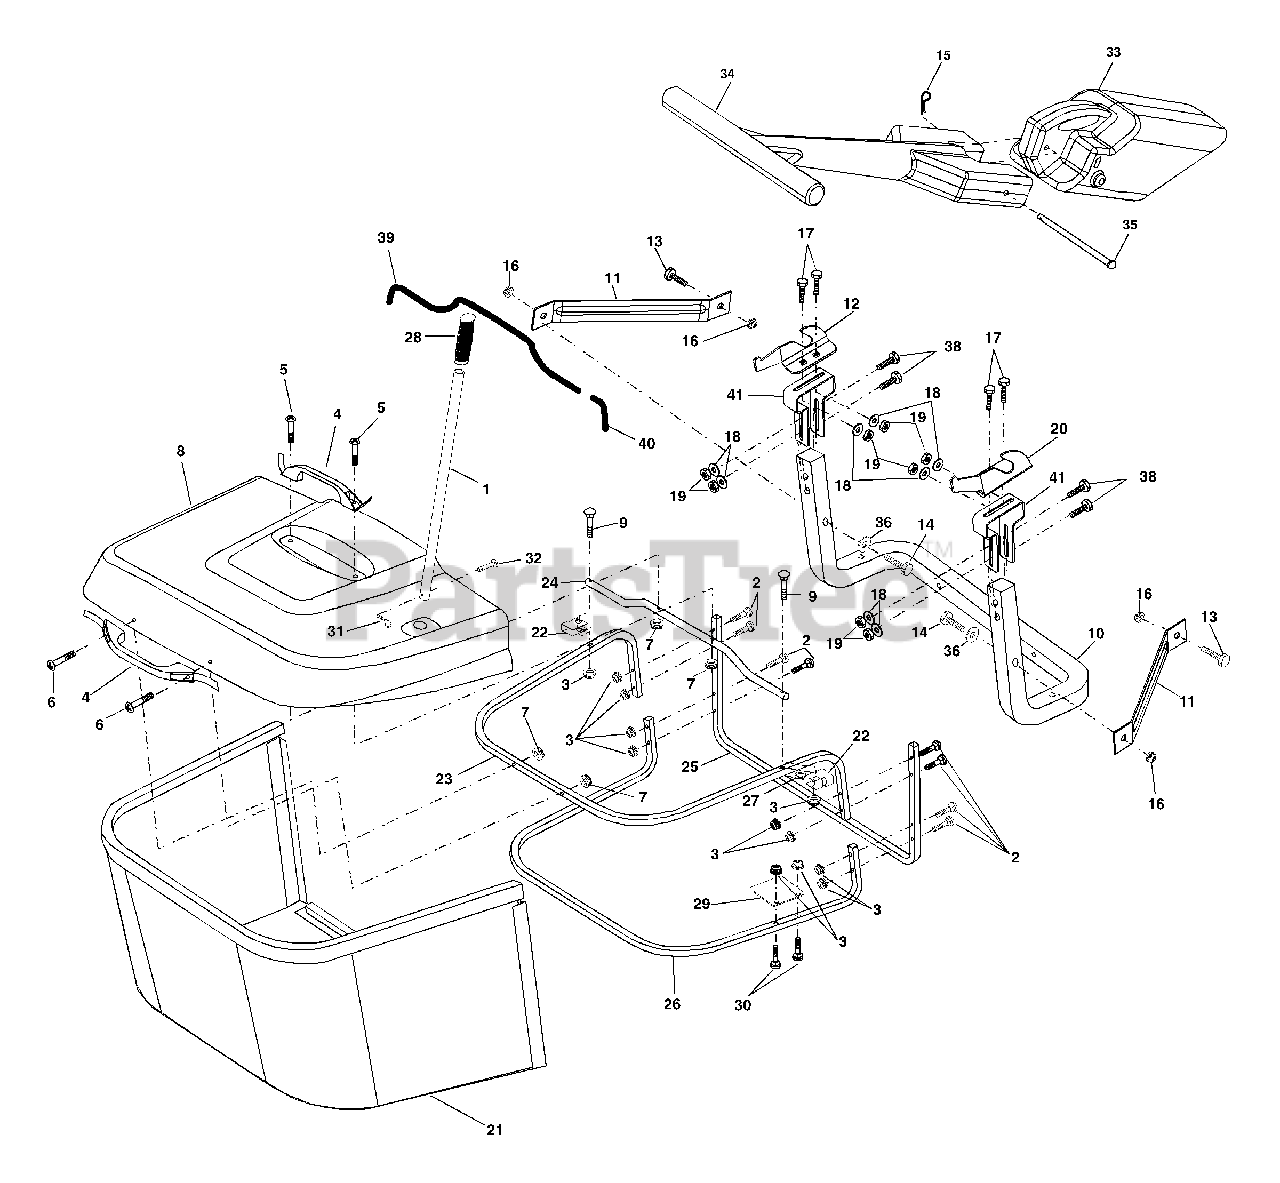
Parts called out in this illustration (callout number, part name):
1	Tube Handle Bagger CRD
2	Bolt Carriage 1/4-20 x 2.0 Gr.5
3	Nut Lock 1/4 Lge Flg Gr. 5 Zinc
4	Handle Bagger w/Lvrs Blk CRD
5	Screw Pan Head #10-24 x 1.50 Blk
6	Screw Pan Hd
7	Nut Wiz Lock Hex Serr/Hd 10-24
8	Cover Bagger Plastic CRD MS422
9	Bolt Carriage 1/4-20 x 2.25d x Gr.5
10	Tube Support Bagger CRD
11	Bracket Support Upper Bag CRD
12	Bracket Horiz Adj Bagger Lh CRD
13	Bolt Rdhd Sht Sqnk 3/8-16 x 3/4
14	Bolt Hex 3/8-16 x 2-1/2 Gr.5
15	Retainer Spring
16	Nut Lock Flg 3/8-16 Unc
17	Bolt Rdhd Sht Sqnk 5/16 -18 Unc x 3/4
18	Washer 11/32 x 3/4 x 16 Ga.
19	Nut Lock Hex W/Ins 5/16-18 Unc Pl
20	Bracket Horiz Adj Bagger Rh CRD
21	Bag Asm CRD
22	Bracket Side Bagger CRD
23	Tube Upper Bagger CRD
24	Tube Pivot Bagger CRD
25	Tube Front Bagger CRD
26	Tube Lower Bagger CRD
27	Bushing Snap Bagger CRD
28	Grip Handle Black
29	Plate Stop Bagger handle CRD
30	Bolt Carriage 1/4-20 x 1 Gr.5
31	Retainer Spring 1" Zinc/Cad
32	Rivet Rd Hd Drilled 3/8 Dia
33	Plug Mulcher 92 CRD
34	Handle Mulcher 92/107 CRD
35	Pin Mulcher 92/107 CRD
36	Washer 13/32 x 1-1/4 x 16 Ga.
38	Bolt 5/16-18 x 2-1/2
39	Seal 26" (Long)
40	Seal 7" (Short)
41	Bracket Vert Adj Bagger CRD
